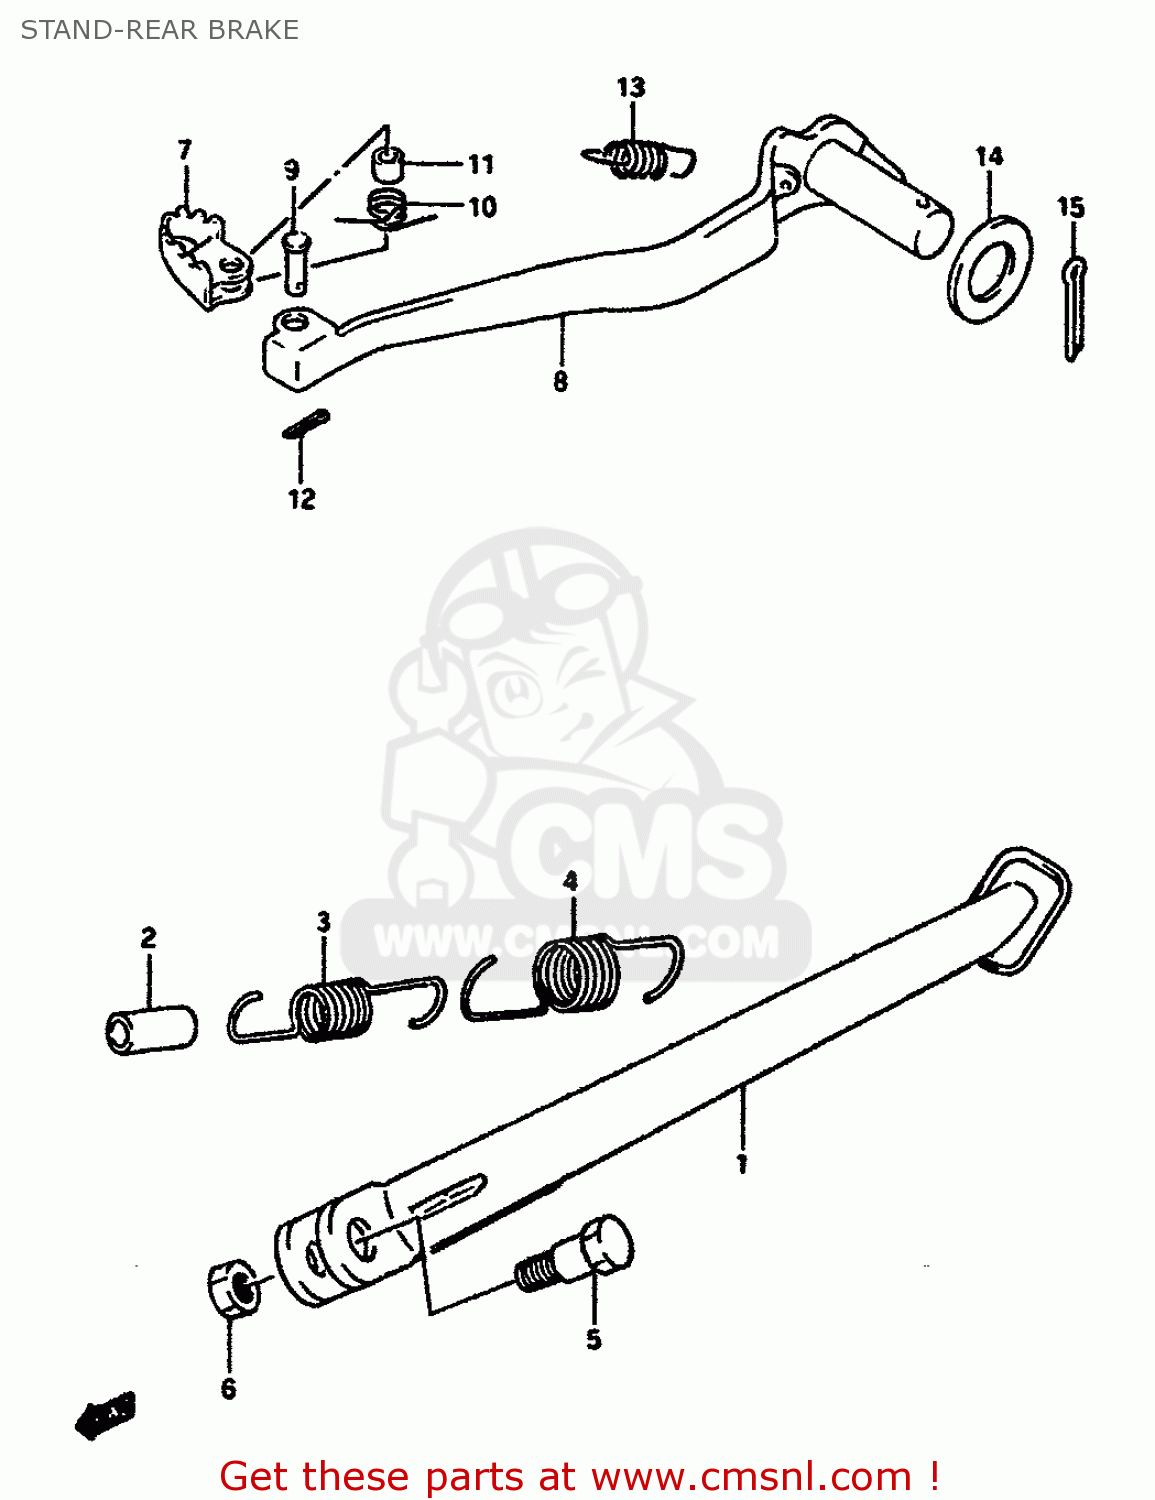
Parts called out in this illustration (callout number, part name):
1	STAND,SIDE
2	HOSE
3	SPRING
4	SPRING
5	BOLT(10X30)
6	NUT
7	PEDAL,BRAKE
8	ARM,BRAKE PEDAL
9	PIN
10	SPRING
11	SPACER(9.2X9X6.5)
12	PIN
13	SPRING
14	WASHER (17.6X34X2)
15	COTTER PIN
